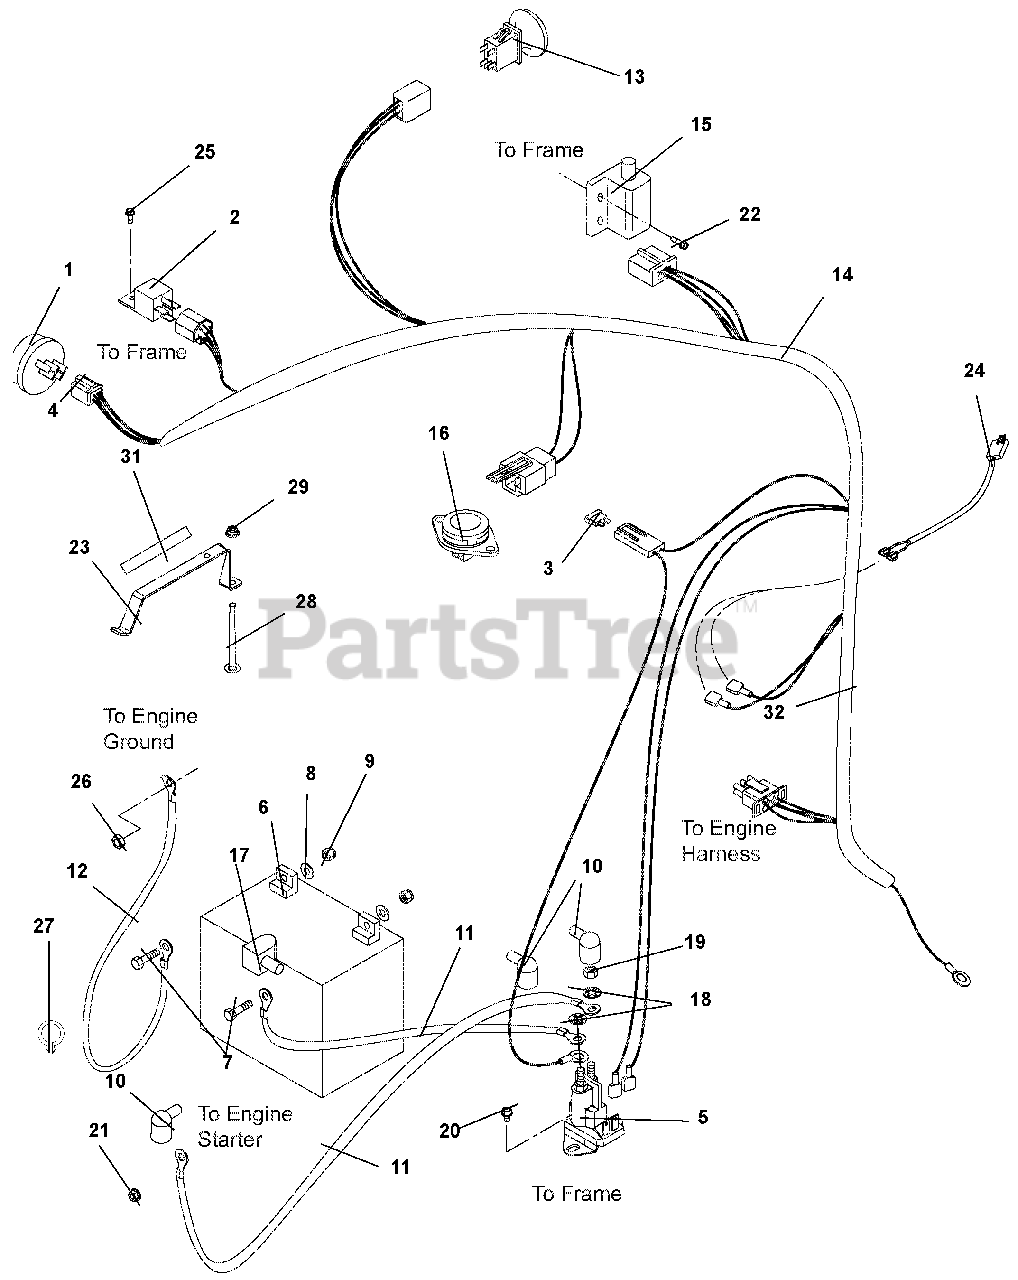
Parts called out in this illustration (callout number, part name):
1	KEY, 03290500 KEYSWITCH
2	RELAY
3	FUSE-25 AMP ATC TYPE
4	KEYSWITCH-IGNITION 3 POS
5	SOLENOID, STARTER (SEALED)
6	BATTERY, 12V 12A-190CCA
7	@BLT-HEX .25-20X.75 GR5 YWZC
8	@WSHR-FL-STL.281X.62X.065 YWZC
9	NUT-KEPS .250-20
10	BOOT, EYELET TERMINAL
11	CABLE,POS W/2 1/4 RING 15.0 LG
12	CABLE, NEGATIVE 26" 6 GA.
13	SWITCH, CLUTCH (YELLOW)
14	HARNESS, ZOOM/ZT WIRE
15	SWITCH- DOUBLE POLE N.O./N.O.
16	SWITCH- SEAT
17	INSULATOR
18	@WSHR-LK-EXT.262X.502X.026YWZC
19	@NUT-LK-CTR .31-18 YWZC
20	@SCR-TAP .25-20X.37 HWH YWZ TR
21	@NUT-LK-TOP-FLG .25-20 YWZC
22	SCR- 12-14X.75 HX W/HD TEK ZC
23	HOLDDOWN, BATTERY, U1&190CCA
24	HARNESS, CLUTCH
25	@SCR-TAP 10-24X.50 HWH TR YWZC
26	@NUT-LK-CTR-JAM .375-16 YWZC
27	WIRE CLIP
28	@BLT-RDHDSQNK .25-20X4.50 G2YZ
29	@NUT-LK-NYL-FLG .25-20 YWZC
30	CABLE TIE LG 5-1/2
